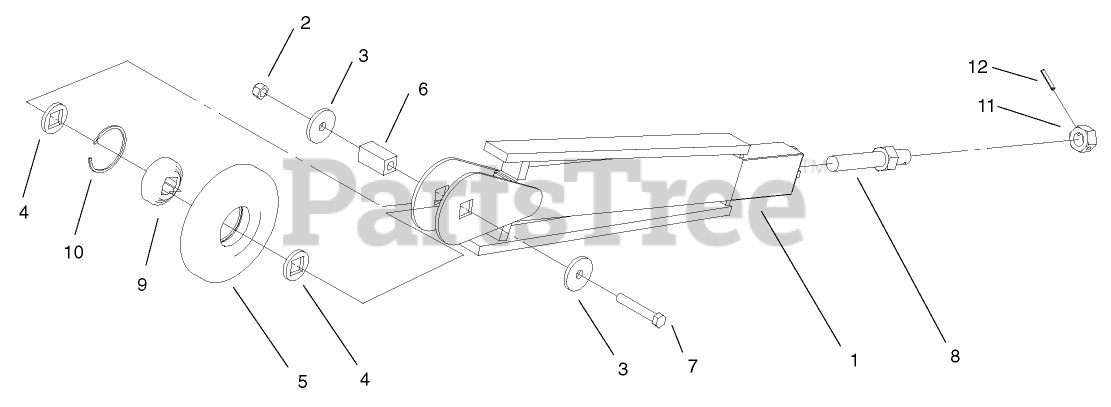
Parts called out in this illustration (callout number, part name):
1	BOOM ASM
2	NUT-LOCK
3	WASHER-ROLLER
4	SPACER-ROLLER
5	ROLLER-NOSE
6	PIN-ROLLER
7	SCREW-HH
8	ADJUSTER ASM
9	BEARING
10	RING-RETAINING
11	PIN-ROLL
12	NUT-HEX
